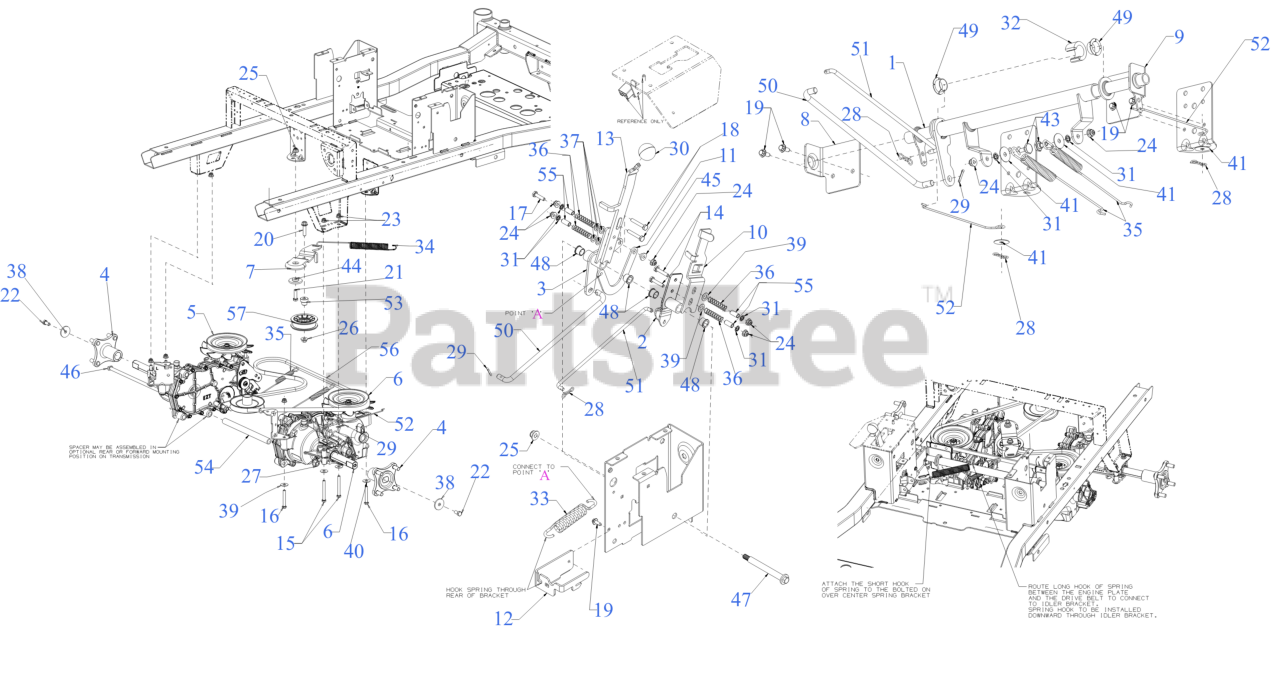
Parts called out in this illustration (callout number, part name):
1	BRAKE PIVOT SHAFT
2	BYPASS LEVER PIVOT ARM
3	PARK BRAKE PIVOT ARM
4	WHEEL HUB ASSEMBLY
5	TRANSMISSION (LH)
6	TRANSMISSION (RH)
7	HYDRO DRIVE IDLER BRACKET
8	BRAKE SHAFT SUPPORT (RH)
9	BRAKE SHAFT SUPPORT (LH)
10	TRANSMISSION BYPASS LEVER
11	OVER CENTER LINK
12	SPRING MOUNTING BRACKET
13	PARK BRAKE LEVER
14	HEX SCREW 1/4-20 x 1.25
15	HEX SCREW 5/16-18 x 2.75
16	HEX SCREW 5/16-18 x 2.25 GR5
17	SCREW 1/4-20 X1.00 GR5
18	SCREW 1/4-20 x 1.50 GR.5
19	SCREW M6-1 x .625
20	HEX HEAD BOLT (3/8-16:1.50 GR8)
21	SCREW 3/8-16 x 1.25 GR5
22	SCREW 3/8-16 x .75 GR 5
23	FLANGE LOCK NUT 5/16-18
24	FLANGE LOCK NUT
26	FLANGE LOCK NUT
27	FLANGE LOCK NUT
28	BOW TIE COTTER PIN 1/4-5/16
29	COTTER PIN
30	PARK BRAKE BALL KNOB
31	RETAINER-BOLT .25ID x .50OD
32	SPACER: .76ID x .75
33	EXTENSION SPRING .57 x 5.38
34	EXTENSION SPRING .75 DIA X 10.27
35	EXTENSION SPRING .60 DIAx8.69
36	COMPRESSION SPRING
37	FLAT WASHER
38	FLAT WASHER .390x1.500x.134
39	WASHER THRUST .375X.70X.030
40	FLAT WASHER
41	FLAT WASHER
43	SHOULDER SCREW
44	SHOULDER SPACER
45	SHOULDER SPACER
46	SUPPORT TUBE ROD
47	SHOULDER SCREW .491x3.937 3/8-16
48	FLANGE BUSHING
49	FLANGE BEARING .75 x 1.125 x .375
50	BRAKE LINK
51	BYPASS LINK
52	HYDRO BYPASS ROD .100 DIA
53	SHOULDER SPACER
54	SUPPORT TUBE
55	SPACER .252x.350x.760
56	TRANSMISSION DRIVE BELT A x 67
57	FLAT IDLER PULLEY 3.00 OD
